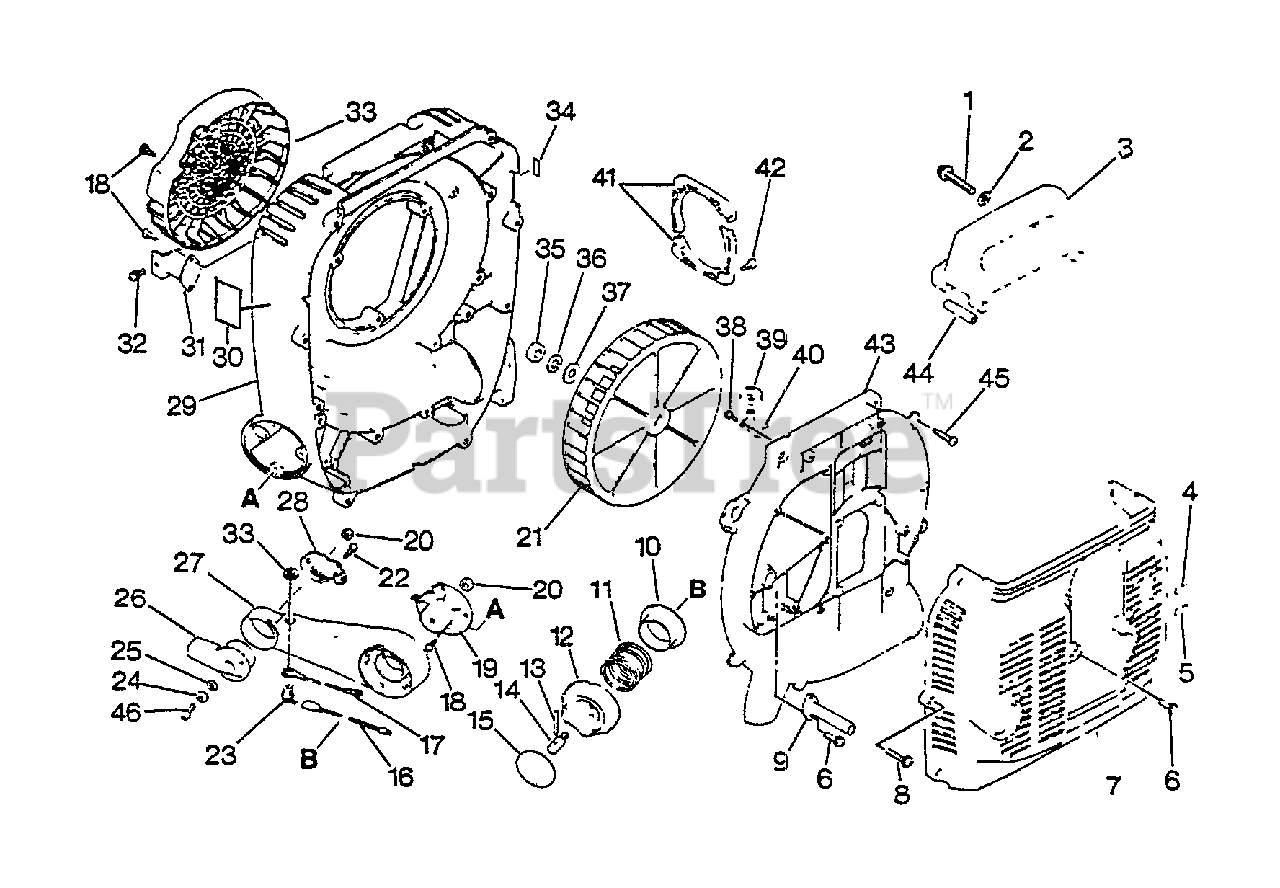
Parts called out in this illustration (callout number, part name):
1	SCREW 6×70
4	LABEL, CAUTION - IDLE
5	LABEL - CAUTION
6	SCREW 4×14
7	COVER, ENGINE
8	SCREW 5×20
9	DUCT, AIR
10	SEAT, SPRING
12	KNOB
15	LABEL
17	LEAD - GROUND
18	SCREW 5×14
19	PLATE
20	NUT, HEX M6
22	SCREW 4×10
23	SWITCH, ON-OFF
26	TRIGGER, THROTTLE
27	BRACKET, THROTTLE LEVER
28	BRACKET, THROTTLE
29	COVER, FAN - INNER
30	LABEL - CAUTION
32	SCREW 5×14
33	SHIELD, DEBRIS
34	LABEL - CHOKE
35	NUT - 10
36	LOCKWASHER - 6
37	WASHER - 10
38	SCREW 4×10
40	PIPE, INTAKE
41	RETAINER
42	SCREW 5×14
43	COVER, FAN - OUTER
45	SCREW 5×25
46	SCREW 6×20
